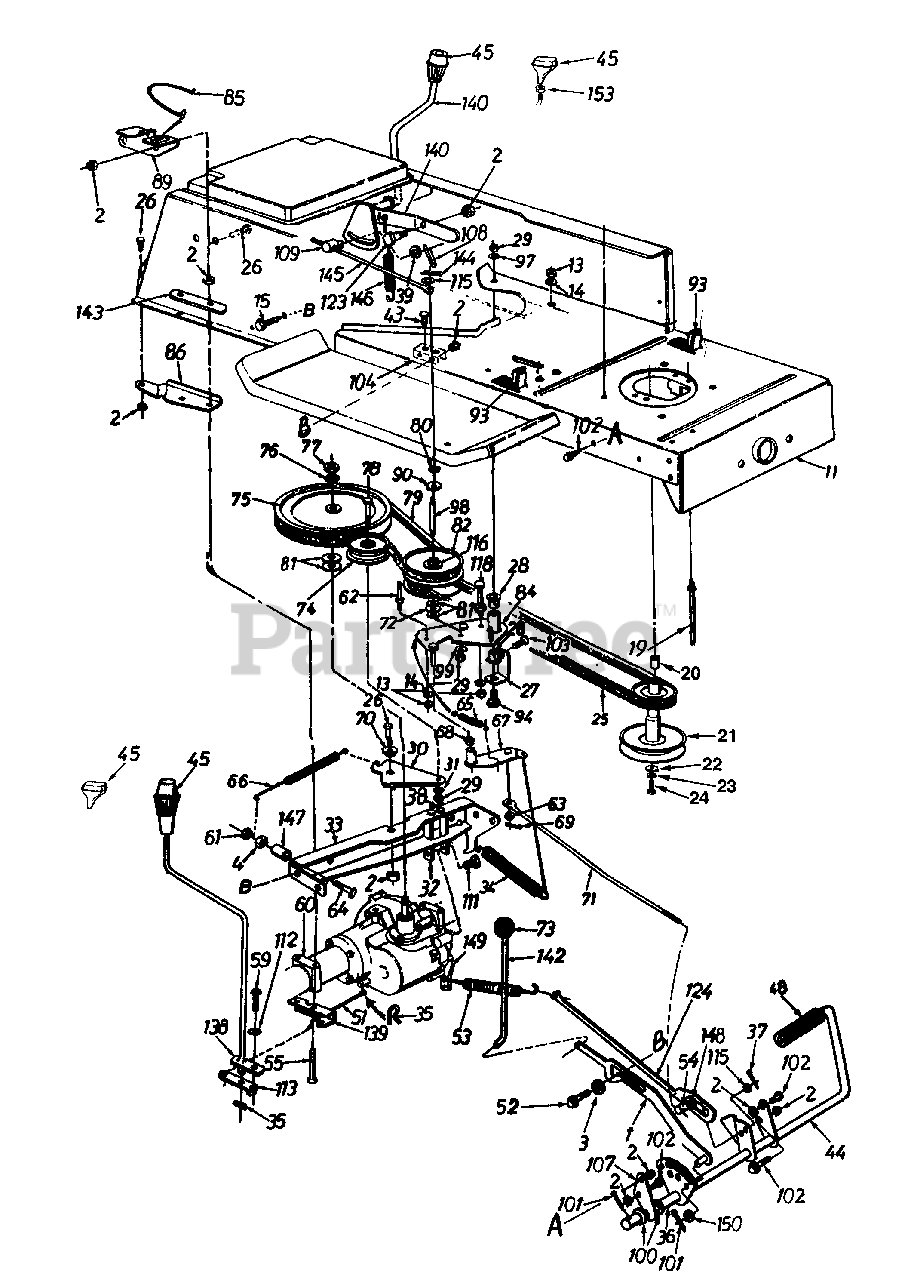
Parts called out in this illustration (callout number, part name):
1	Parking Brake Lockout Brkt. Ass'y.
2	Hex Sems Nut 5/16-18 Thd.
3	Fl-Wash..442" I.D. x 1.38" O.D.
4	Hex Nut 5/16-24 Thd.
14	L-Wash. 1/4" I.D.
15	Hex TT-Tap Scr. 5/16-18 x .62"
19	Belt Guard Pin
20	Spacer 1" I.D.
21	Engine Pulley
22	Shld. Spacer .445" I.D.
23	L-Wash. 7/16" I.D.
24	Hex Bolt 7/16-20 x 1.5" Lg.
25	Variable Speed Belt
26	Hex Bolt 5/16-18 x .75" Lg.
27	Bearing Shaft Bracket Ass'y.
28	Flanged Nyliner Brg..63" I.D. x .6" Lg.
29	Hex Nut 3/8-24 Thd.
30	Idler Bracket
31	L-Wash. 3/8" I.D.
35	Inter. Cotter Pin
36	Spacer .63" I.D.
37	Cotter Pin 1/8" Dia. x 1.0" Lg.
38	Self-Tap Scr. 5/16-18 x .5" Lg.
39	Fl-Wash..51" I.D. x .75"
43	Hex Wash. Hd. S-Tap Scr. 1/4-20 x .50" Lg.
48	Foot Pad
51	Shift Lever Rod
52	Shld. Bolt .437"
53	Ext. Spring 3.6"
54	Ferrule
55	Hex Bolt 5/16-18 x 3.25"
59	Hex Bolt 1/4-28 x .62" Lg.
60	Transaxle Complete
61	Hex L-Nut 1/4-20 Thd.
62	Belt Guard Pin 1/4-20 Thd.
63	Fl-Wash. .34" I.D. x .68" O.D.
64	Hex Wash. TT-Tap Scr. 1/4-20 x 1.75"
65	Ext. Spring 2.59" Lg.
66	Ext. Spring .5" O.D. x 4.35"
68	Flanged Bearing
69	Cotter Pin 3/32" Dia.
70	Shoulder Spacer .27" Lg.
71	Speed Control Link
72	Truss Bearing .56 Dia x 1.25"
73	Ball Knob
74	Fl-Idler Pulley 3.25" x .75"
75	"V"-Pulley
76	L-Wash. 1/2" I.D.
77	Hex Jam Nut 1/2-20 Thd.
78	Hex Bolt 3/8-24 x 1.75" Lg.
79	Variable Speed Belt
80	Snap Ring .56" Dia.
81	Fl-Wash. .56" I.D. x 1.0" O.D.
82	Variable Speed Pulley Ass'y. 5" O.D.
90	Teflon Washer .565" I.D
93	Safety Switch (Clutch)
94	Shld. Bolt 3/8-24 x 3.12" Lg.
97	Bell-Wash. 38" I.D. x .88"
98	Shaft
99	Bell-Wash .39" I.D. x 1.12"
100	Fl-Wash. .64" I.D x .94"
101	Cotter Pin 3/32" Dia. x 1" Lg.
102	Hex Wash. Hd. Scr. 5/16-18 x .62" Lg
103	Hex Wash. Hd. AB-Tap Scr. .75" Lg.
104	Bracket
109	Ferrule
111	Hex Wash Tap Scr.
112	Bell-Wash. .265" I D x .75"
113	Shift Lever Link Ass'y.
115	Fl-Wash. 385" I.D. x .62"
116	Needle Brgs.
118	Hex Bolt 1/4-20 x 3.5" Lg.
123	Shld. Bolt .437" Dia. x .162"
124	Brake Rod Ass'y.
138	Shift Lever Ass'y.
139	Shift Lever Support Brkt.
140	Speed Selector Lever Ass'y.
142	Brake Lockout Rod
144	Cotter Pin 1/8" x 3/4" Lg.
145	Speed Selector Rod
146	Ext. Spring 3.97" Lg.
147	Spacer 326" I D x .47"
148	Fl-Wash. 5/8" I.D x 1.25"
149	Actuating Arm
150	Fl-Wash. .385" I.D. x .62" O.D.
153	Hex Jam Nut 3/8-16 Thd
